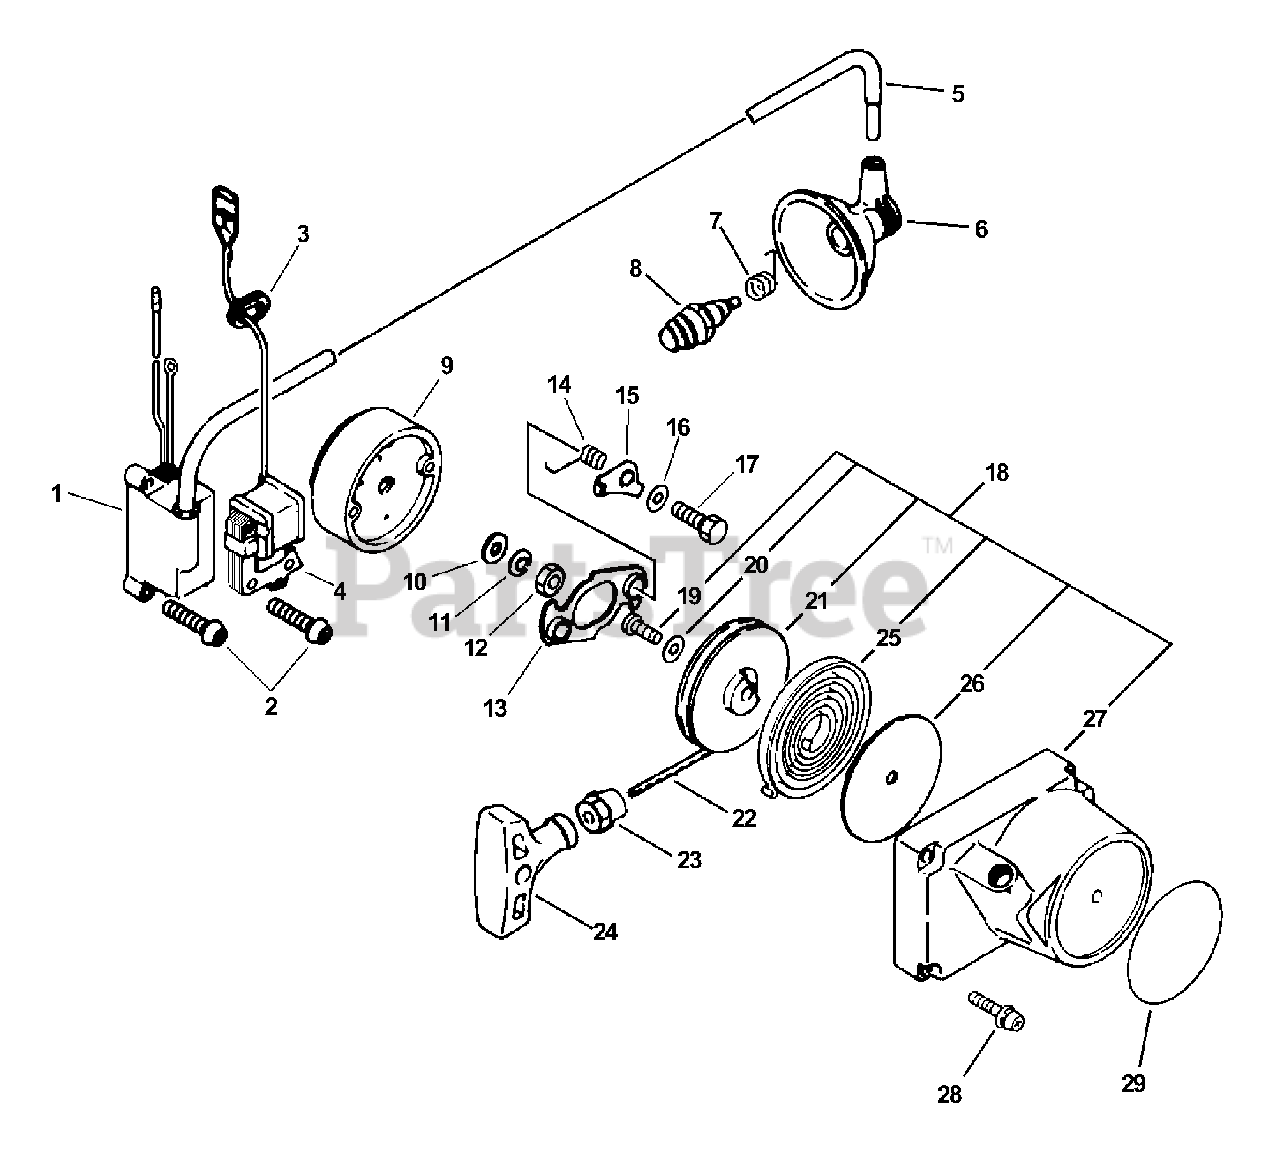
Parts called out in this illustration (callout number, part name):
1	COIL, IGNITION
2	SCREW - 4X20
4	COIL, EXCITER
6	CAP, SPARK PLUG
7	TERMINAL, SPARK PLUG CAP
8	SPARK PLUG -- BPM-8Y
9	FLYWHEEL
10	WASHER - 8
11	LOCKWASHER - 8
13	HOLDER, PAWL
14	SPRING, RETURN
15	PAWL, STARTER
16	WASHER - 5
17	BOLT - 5X20
18	STARTER ASSY
19	SCREW - 4X10
21	REEL, ROPE
22	ROPE, STARTER - 3X850
23	GUIDE, ROPE
24	GRIP, STARTER
25	SPRING, REWIND
26	PLATE, STARTER
27	CASE, STARTER
28	SCREW - 5X25
29	LABEL - ECHO
